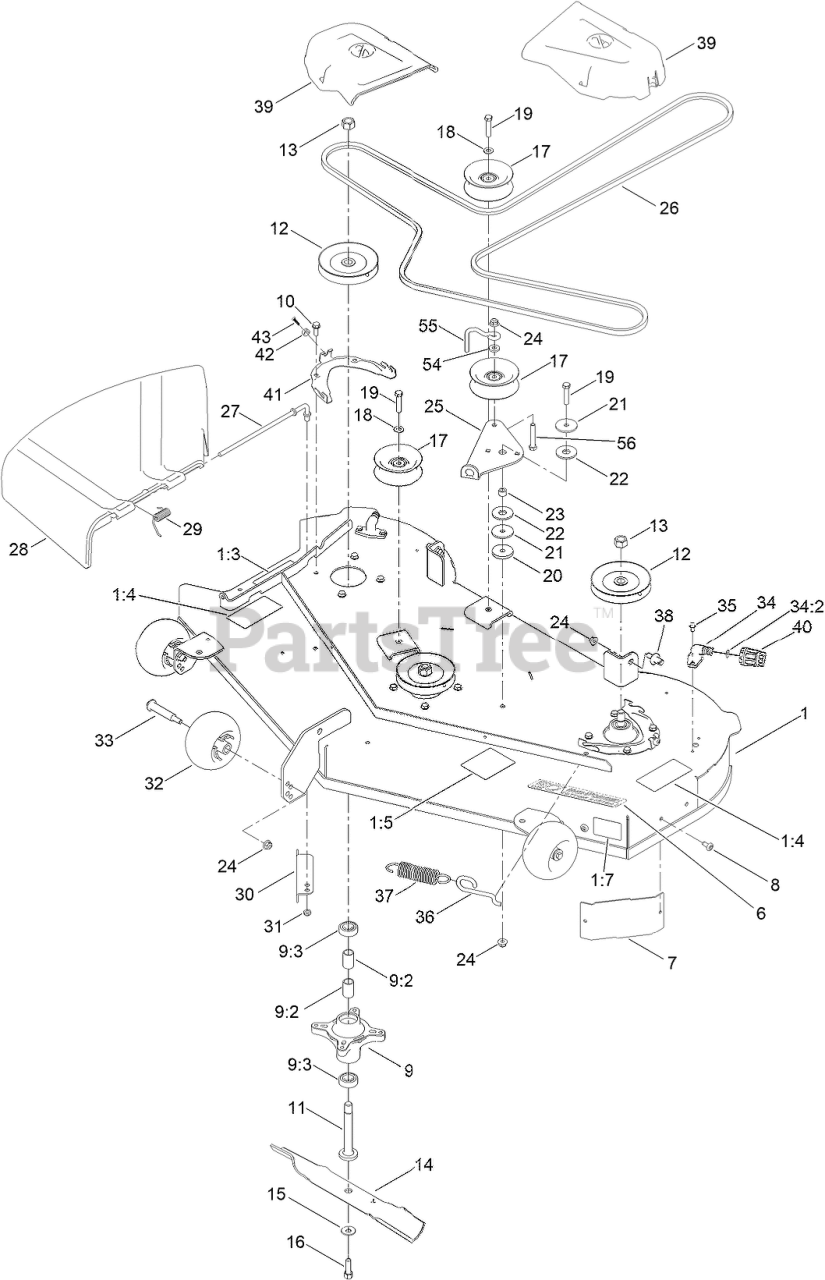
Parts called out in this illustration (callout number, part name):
1	50 INCH DECK AND DECAL ASM
1:3	DECAL-DANGER
1:4	DECAL-DANGER, DECK
1:5	DECAL-ROUTING, BELT
1:7	DECAL-SCALP, ANTI
6	DECAL - DECK
7	BAFFLE-CORNER
9	SPINDLE ASM
9:2	SPACER
9:3	BEARING-BALL
10	SCREW-TAPTITE
11	SHAFT-SPINDLE
12	PULLEY
13	NUT-HEX
14	BLADE-HI LIFT
15	WASHER-BELLEVILLE
16	SCREW-HH
17	PULLEY-IDLER, FLAT
18	WASHER-FLAT
19	SCREW-HH
20	WASHER-PLAIN
21	WASHER-REBOUND
22	WASHER-FRICTION, COMPOSITE
23	SPACER
24	NUT-HF, NI
25	ARM-IDLER
26	V-BELT
27	ROD-PIVOT
28	DEFLECTOR-DISCHARGE
29	SPRING-TORSION
30	BAFFLE-CUTOFF
32	ROLLER-SCALP, ANTI
33	BOLT-SHOULDER
34	FITTING-WASHOUT
34:2	O-RING
35	SCREW-HWH
36	HOOK-RETURN SPRING
37	SPRING-EXTENSION
38	PIN-DECK
39	COVER-BELT
40	CONNECTOR-HOSE
41	BRACKET-COVER, BELT
42	SPACER-NOTCHED
43	SCREW-PPH
54	SPACER-HUB, BLOWER
55	BELT GUIDE - IDLER
56	SCREW-HH
